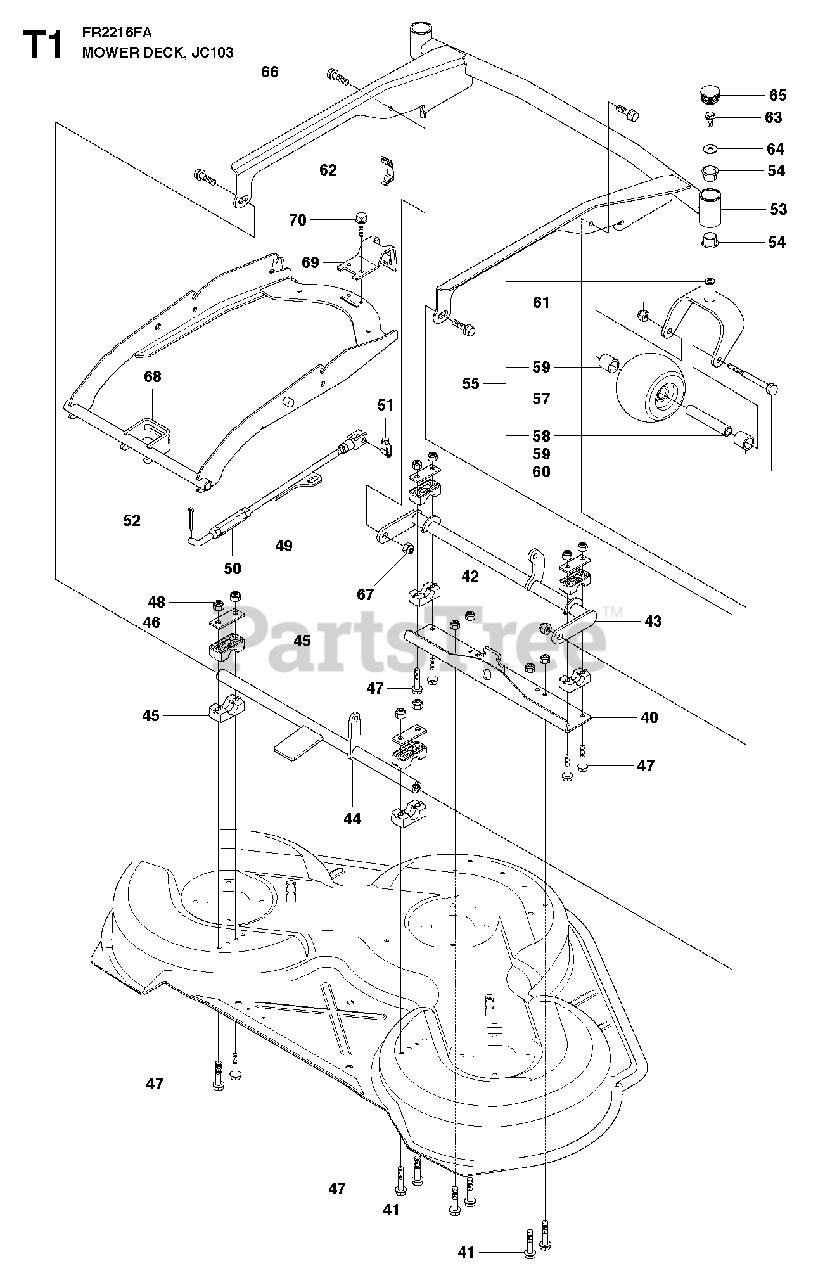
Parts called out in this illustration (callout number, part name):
42	LOCKNUT M8
48	LOCKNUT M8
49	PARALLELL ROD ASSY
50	PARALLEL ROD
51	RETAINER
52	SPLIT PIN
57	DECK ROLLER, FRONT
58	PIPE
59	SPACER
61	NUT
62	CLIP GRAY
67	LOCKNUT M8
